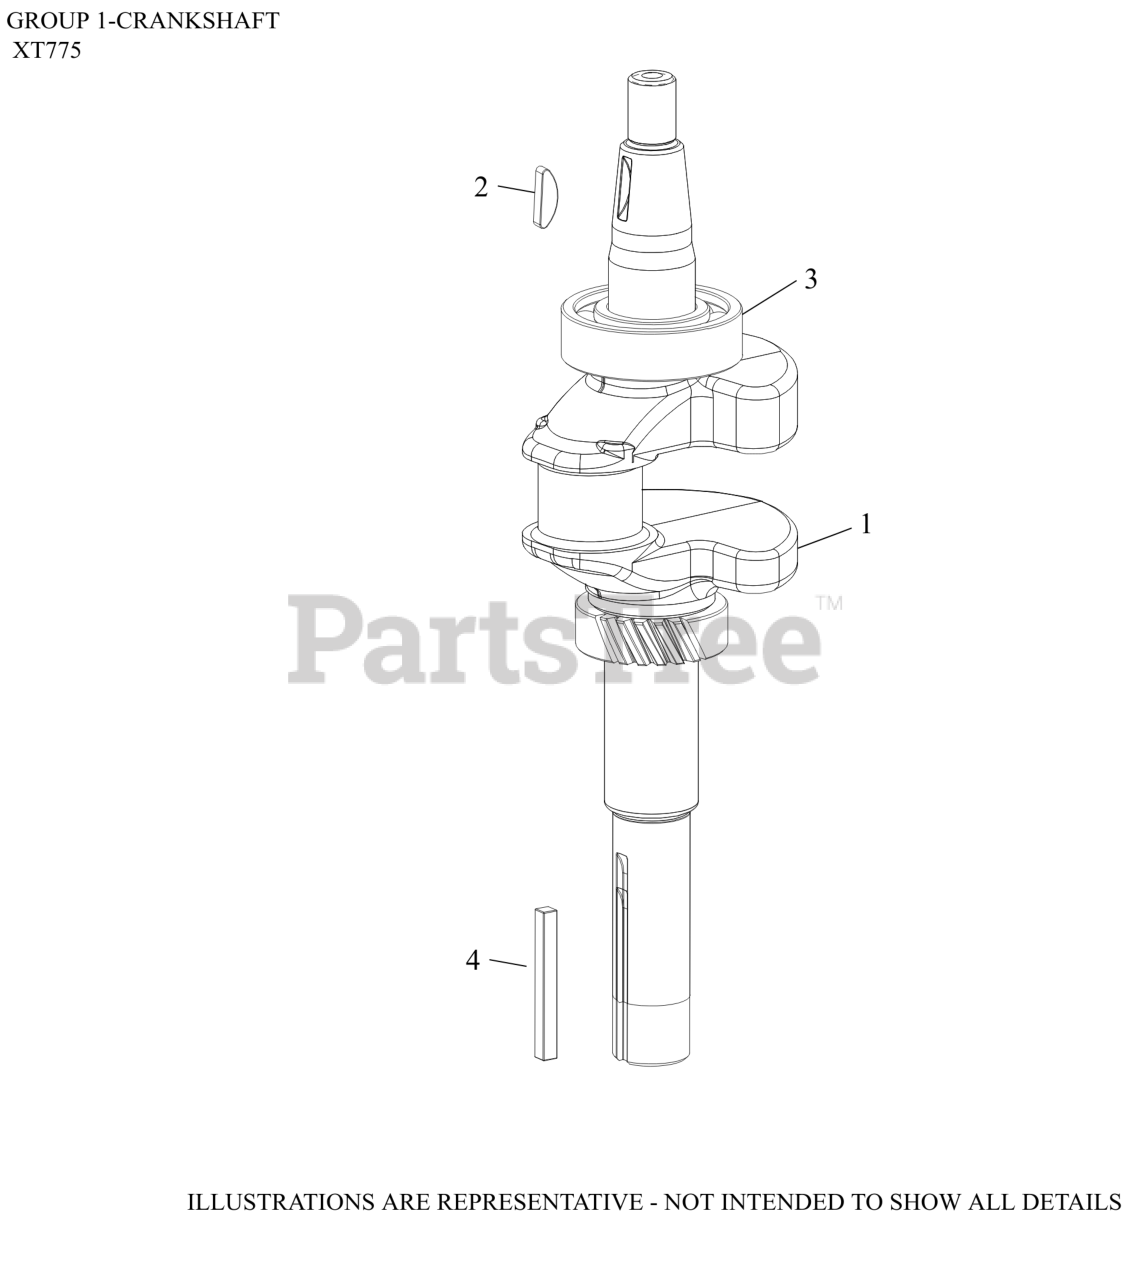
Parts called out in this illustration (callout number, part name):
1	CRANKSHAFT ASSEMBLY
2	KEY, FLYWHEEL
3	BEARING, BALL
